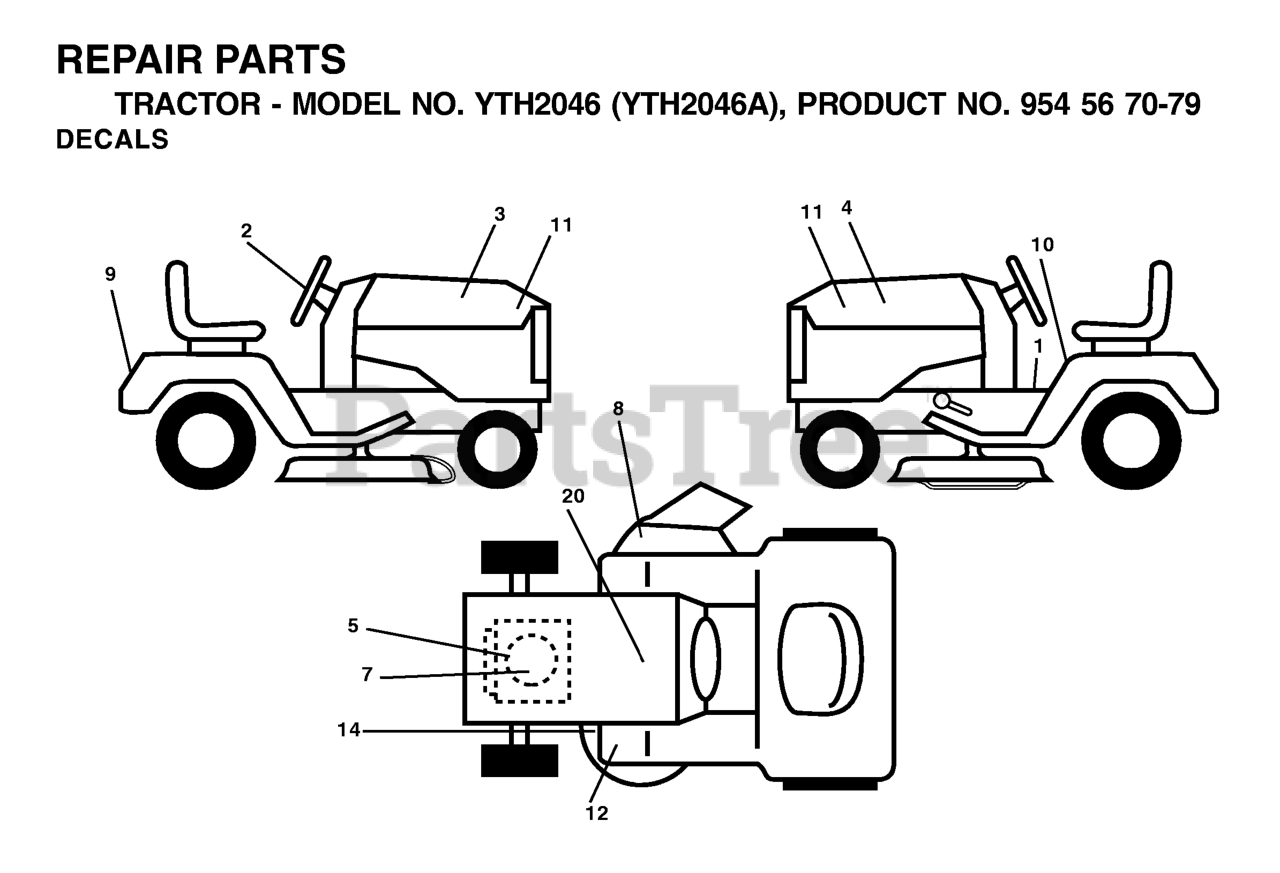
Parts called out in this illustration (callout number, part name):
2	DECAL.WHEEL.STEERING.HUSQ.PERM
8	DECAL.WARN.KEEP.HAND.AWAY
9	DECAL, FENDER
10	DECAL FENDER DANGER
14	DECAL V-BELT SCHEMATIC
20	DECAL BTRY SYMBOLS
